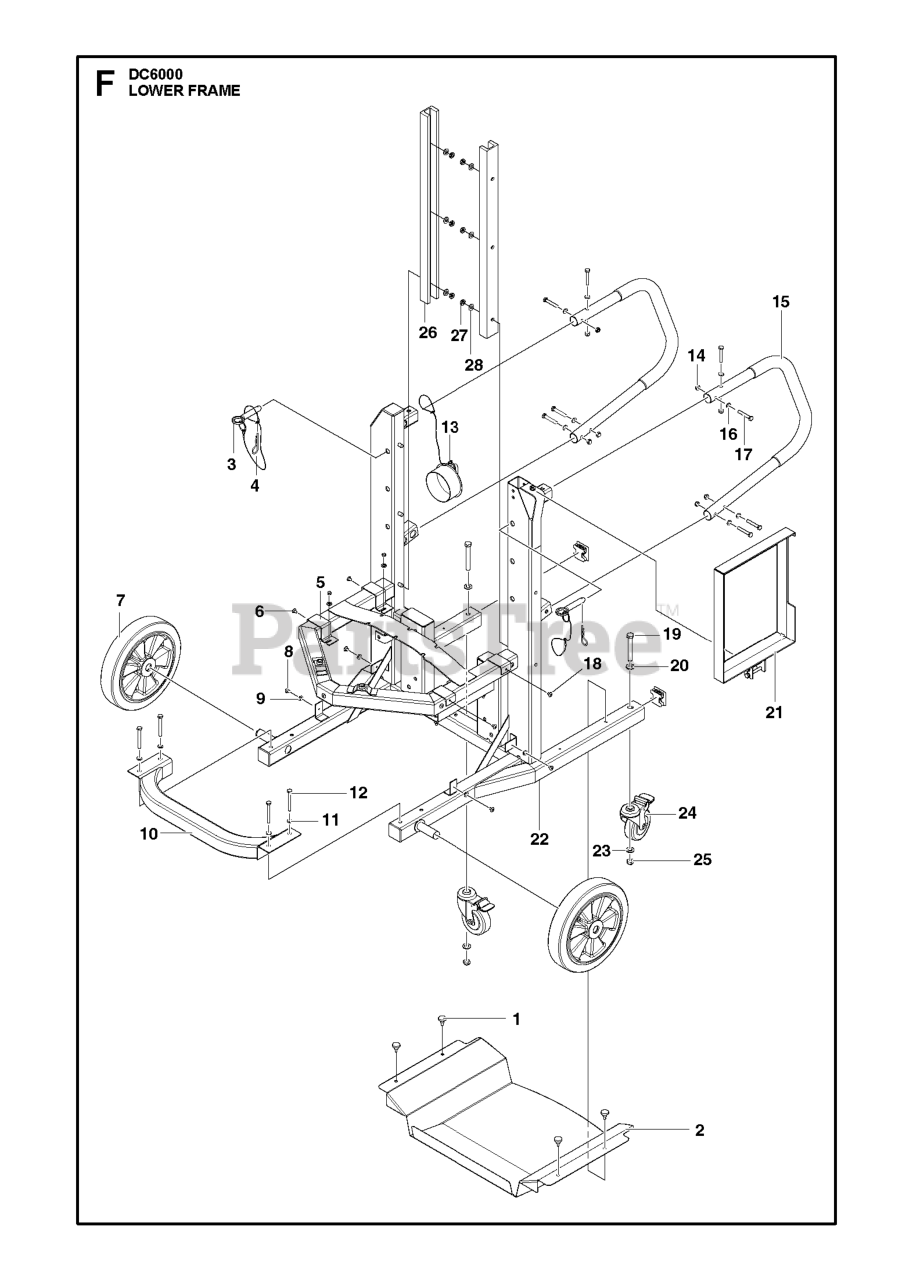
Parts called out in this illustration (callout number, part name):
11	WASHER - 15X7.3X1.6
14	NUT LOCK - M8, NYLOCK
17	SCREW M6S 8X50 NLA
20	WASHER - M12
28	WASHER
